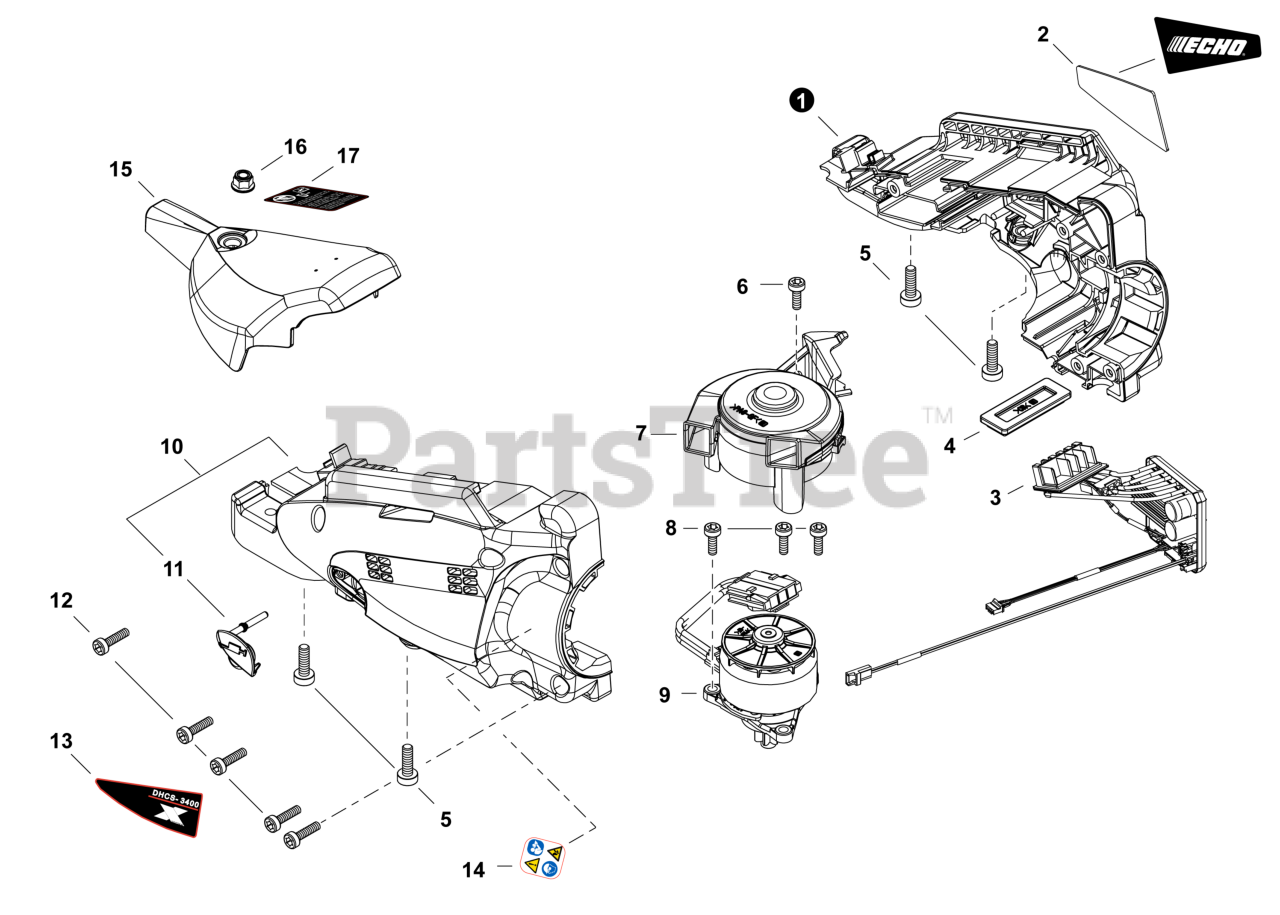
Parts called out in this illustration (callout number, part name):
1	COVER, MOTOR - RIGHT
2	LABEL - ECHO
3	CONTROL BOARD ASSY
4	CUSHION
5	BOLT, TORX 5x16
6	BOLT, TORX 4x12
7	CASE ASSY, FAN
8	BOLT, TORX 4x12
9	MOTOR ASSY
10	COVER ASSY, MOTOR - LEFT
11	CAP, CUP GREASE
12	BOLT, TORX 4x16
13	LABEL - MODEL DHCS-3400
14	LABEL - CAUTION - ISO
15	COVER, GEAR CASE
16	NUT, FLANGE M5
17	LABEL - CAUTION - UL
